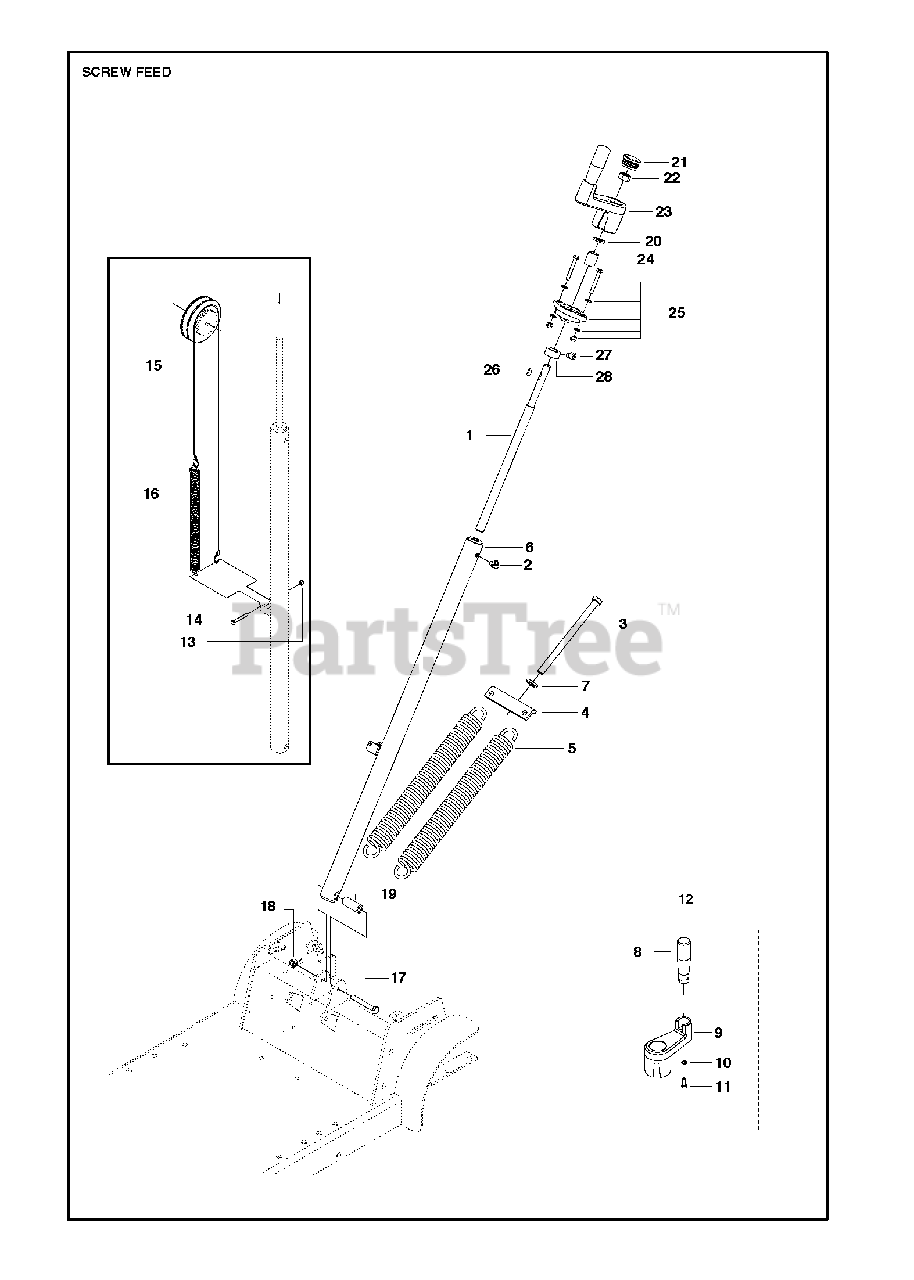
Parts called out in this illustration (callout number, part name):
7	WASHER
10	WASHER
13	HEXAGON LOCKING NUT
18	HEXAGON LOCKING NUT
20	WASHER
